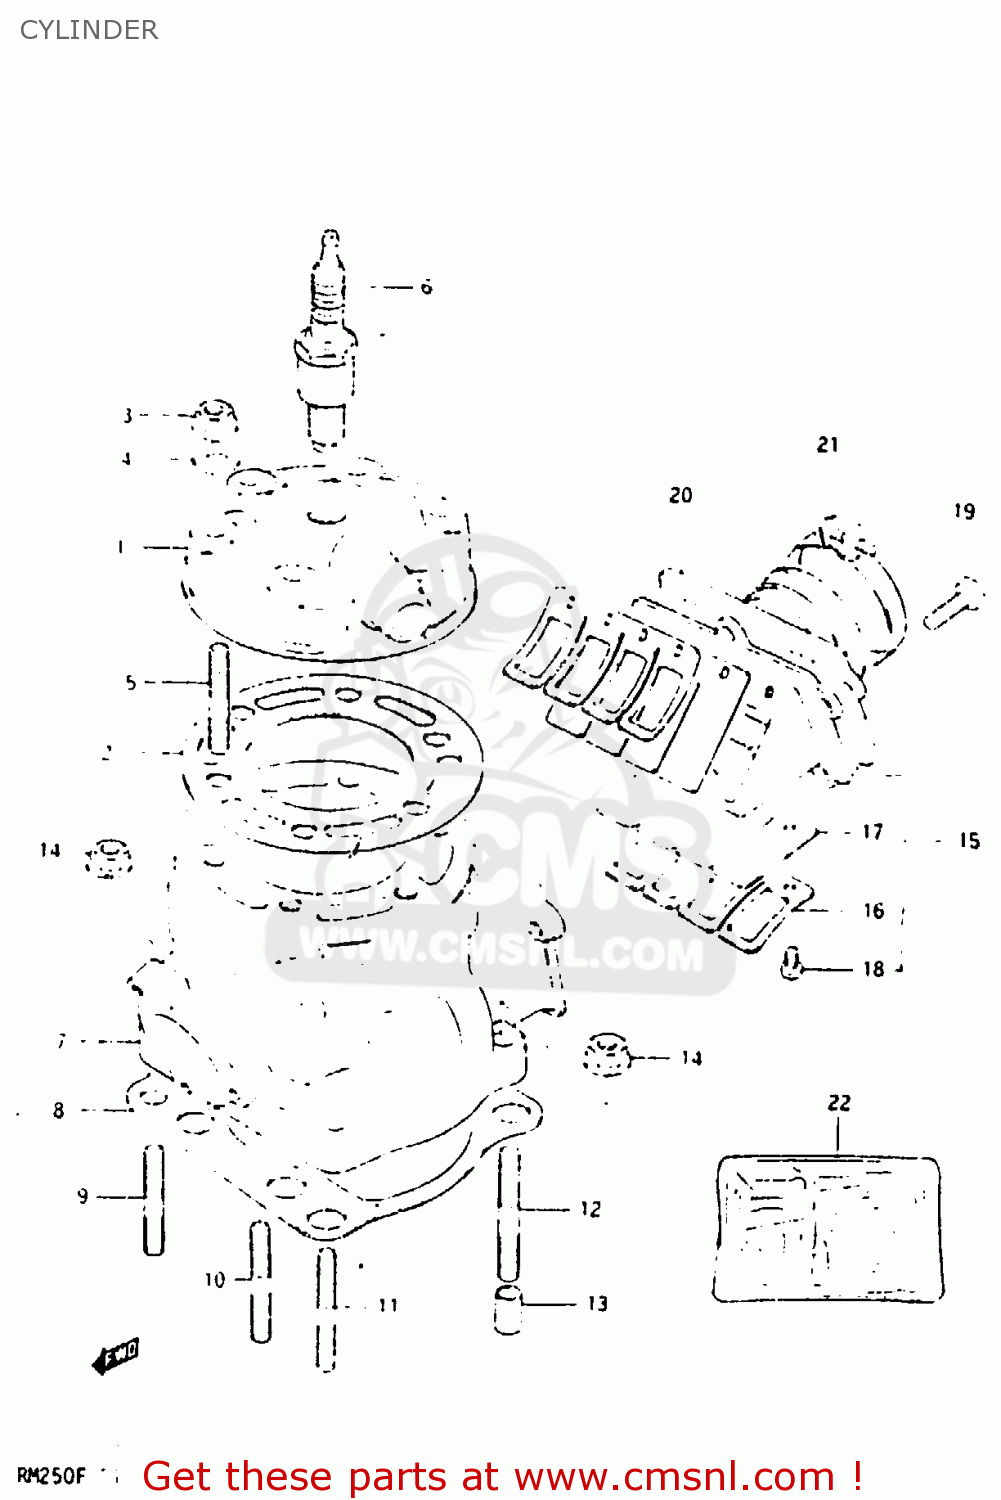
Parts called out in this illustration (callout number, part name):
1	CYLINDER HEAD
2	GASKET,CYLINDER HEAD
3	NUT 8MM
4	WASHER (8.5X19X2.3)
5	STUD
6	SPARK PLUG (NGK,BR8EV)
7	CYLINDER
8	GASKET,CYLINDER (MCA)
9	BOLT,STUD
10	BOLT,STUD
11	BOLT,STUD
12	BOLT,STUD
13	PIN
14	NUT 8MM
15	VALVE ASSEMBLY,REED
16	STOPPER,REED VALVE
17	VALVE,REED
18	SCREW
19	BOLT
20	PIPE,INTAKE
21	CLAMP
22	GASKET (MCA)
